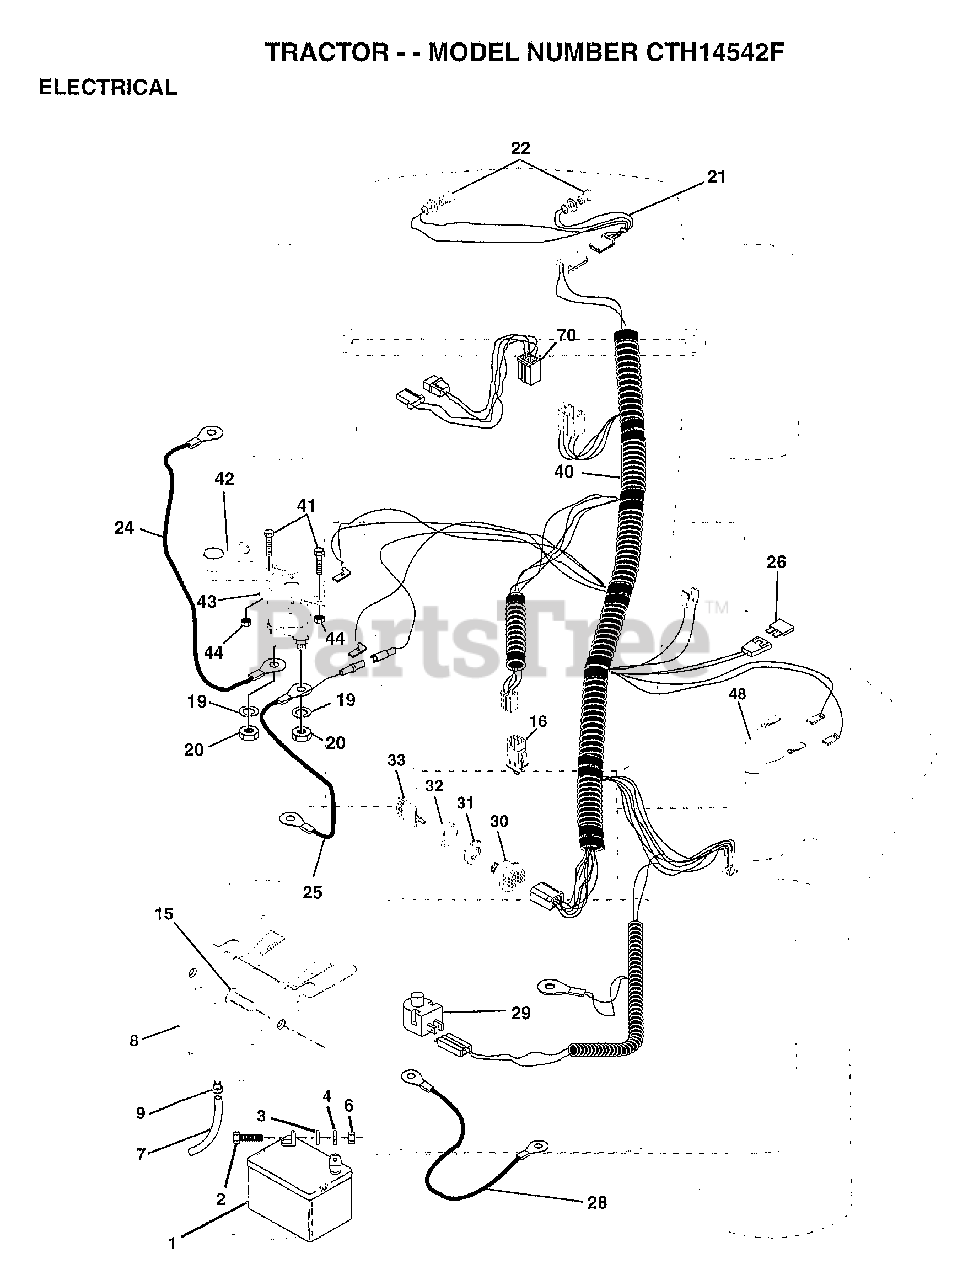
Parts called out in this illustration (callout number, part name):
2	BOLT LT
3	WASHER
4	LOCKWASHER
7	TUBE T
8	"CASE,BATTERY.MECH"
9	HOSE CLAMP T
15	FASTNER.SNAP-IN
16	SWITCH INTERLOCK
20	NUT
21	"HARNESS,LIGHT SOC"
22	HEADLAMP BULB
24	CABLE.BTRY.6GA.38
25	CABLE.BTRY.6GA.RD
26	FUSE HYT
28	CABLE T
29	SWITCH SEAT
30	SWITCH IGN 4POS
31	NUT IGNITION
32	COVER KEY SWITCH
33	KEY
40	HARNESS IGNITION
41	BOLT HXHD FIN
44	NUT HXKEP 1/4X20
48	ADAPTER AMMETER
70	HARNESS.ENG.DUAL
